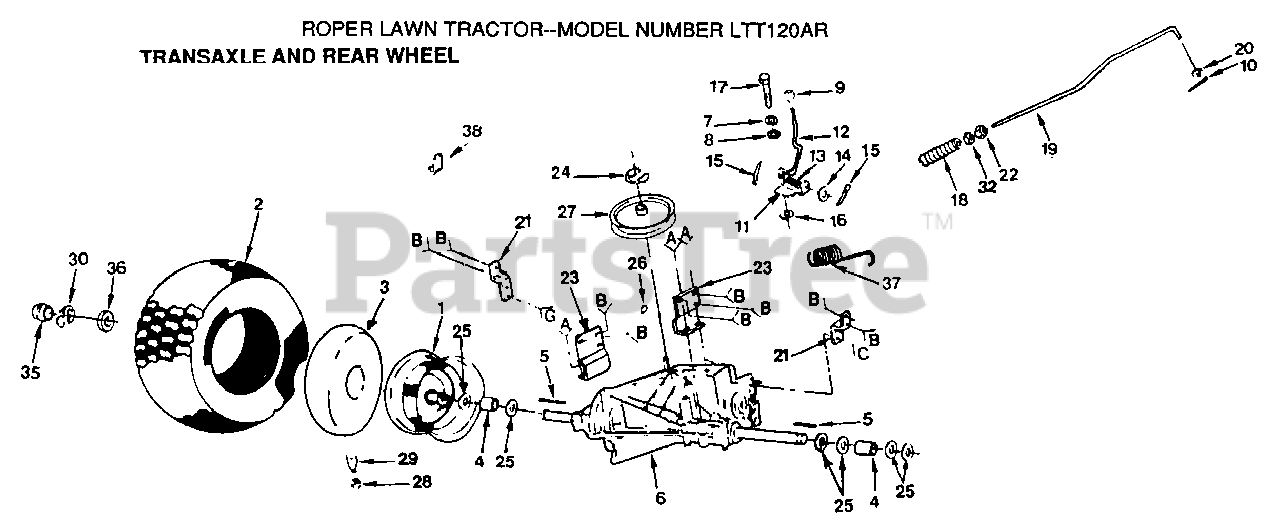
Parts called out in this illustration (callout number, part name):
3	TUBE.18X9.5-8
4	SPACER LT
6	No Desciption for Part
7	LOCKWASHER
8	WASHER LT
9	KNOB.DUCKHEAD.1/2
10	COTTER PIN
11	PLATE SHIFT LT
12	ROD SHIFT
13	SPRING LT
14	WASHER
15	PIN COTTER 1/8
16	"LINK, CLUTCH T"
18	SPRING ROD LT
19	BRAKE ROD LT
20	WASHER
21	STRAP TORQUE
22	NUT
23	BRACKET LT
25	WASHER
28	VALVE CAP
29	VALVE STEM LT
30	E-RING LT
35	HUB CAP
36	WASHER
38	CLIP T
